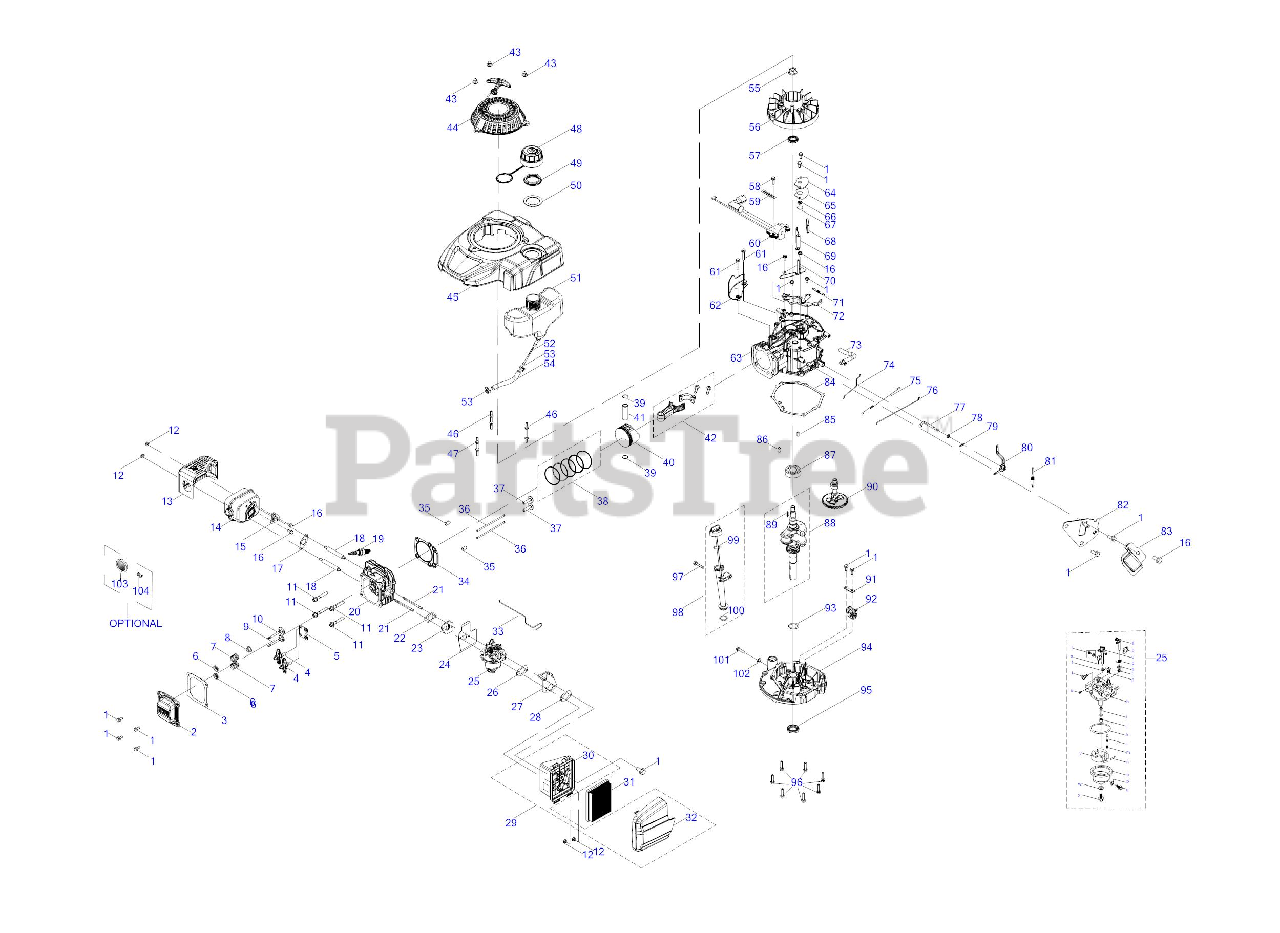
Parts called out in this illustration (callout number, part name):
1	Bolt M6X14
2	Valve Cover
3	Valve Cover Gasket
4	Rocker Arm Assembly
5	Push Rod Guide
6	Valve Spring Retainer
7	Valve Spring
8	Intake Valve Seal
9	Exhaust Valve
10	Intake Valve
11	Bolt M8X54 Cylinder Head
13	Muffler Shield
14	Muffler Assembly
15	Choke Thermal Control
16	Bolt M6X12
17	Muffler Gasket
18	Muffler Stud M6X95
19	Spark Plug/F5RTC
20	Cylinder Head
21	Carb Stud M6X87
22	Carburetor Insulator Gasket
23	Carburetor Insulator
24	Carburetor Gasket
25	Carburetor Assembly
26	Air Filter Bracket Gasket
27	Air Filter Bracket
28	Air Filter Base Gasket
29	Air Filter Assembly
30	Air Filter Base
31	Air Filter Element, Paper
32	Air Filter Cover
33	Temp Control Linkage
34	Cylinder Head Gasket
35	Cylinder Head Dowel Pin 10X16
37	Tappet
38	Piston Ring Set
39	Piston Pin Snap Ring
41	Piston Pin
42	Connecting Rod Assembly
43	Starter Acorn Nut
44	Starter Recoil Assembly
45	Engine Shroud Assembly
46	Shroud Stud M6X78.5
47	Shroud Stud M6X74
48	Fuel Cap Assembly
49	Fuel Tank Nut
50	Fuel Tank Upper Grommet
51	Fuel Tank
52	Fuel Filter
53	Fuel Hose Clamp
54	Fuel Hose
55	Flywheel Nut M14
56	Flywheel
57	Upper Crankshaft Seal
58	Bolt M6X20
59	Flexible Clamp
60	Ignition Coil Assembly
61	Bolt M6X25
62	Engine Brake Cover Plate
63	Crankcase
64	Breather Cover Plate
65	Breather Gasket
66	Breather Valve Spring
67	Breather Valve
68	Breather Screen
69	Air Vane
70	Air Vane Bracket
71	Brake Spring
72	Brake Assembly
73	Breather Hose Assembly
74	Choke Linkage
75	Throttle Linkage
76	Throttle Linkage Spring
77	Governor Arm Shaft
78	Governor Seal
79	Governor Arm Shaft Cotter Pin
80	Governor Arm Assembly
81	Governor Spring
82	Component Bracket
83	Governor Shield
84	Crankcase Cover Gasket
85	Crankcase Cover Dowel Pin 7X14
86	Crankcase Cover Dowel Pin 9X14
87	Main Bearing
88	Crankshaft Assembly
89	Flywheel Key
90	Camshaft Assembly
91	Governor Gear Mounting Plate
92	Governor Gear/Shaft Assembly
93	Crankshaft Thrust Washer
94	Crankcase Cover
95	Lower Crankshaft Seal
96	Bolt M6X28
97	Bolt M6X35
98	Dipstick Assembly
99	Dipstick / Oil Fill Tube O-Ring
100	Dipstick / Oil Fill Tube O-Ring
101	Oil Drain Plug
102	Oil Drain Plug Washer
103	Spark Arrestor
104	Spark Arrestor Screw
